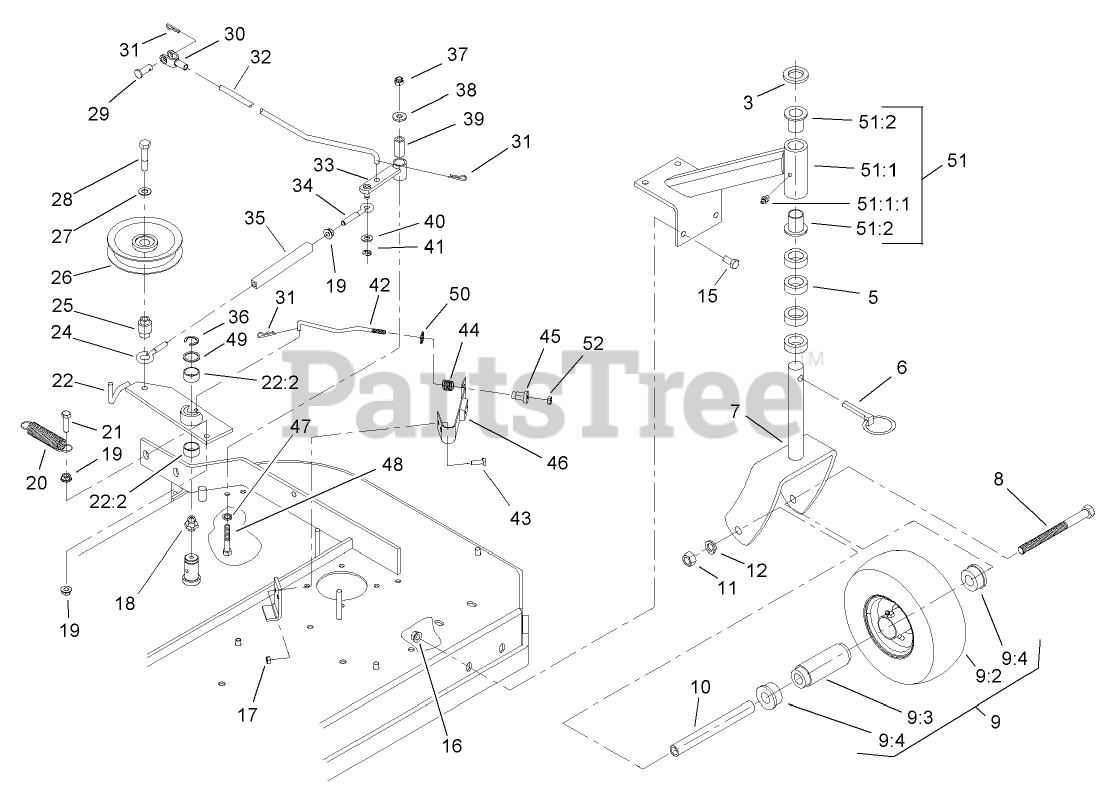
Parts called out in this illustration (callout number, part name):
3	WASHER-FLAT
5	SPACER-CASTER
7	FORK
8	SCREW-HH
9	WHEEL AND TIRE ASM
9:3	BEARING
9:4	BUSHING
10	SPACER
11	NUT-HH
12	WASHER-LOCK
15	SCREW-HH
16	NUT-HHF, WHIZ
17	NUT-LOCK, NI
18	FITTING-GREASE
19	NUT-HF
20	SPRING-EXTENSION
21	SCREW-HH
22	Idler Arm ASM
22:2	SLEEVE-BEARING
24	EYEBOLT-THREAD, LH
25	BUSHING-ENGAGEMENT
26	PULLEY-IDLER
27	WASHER-BELLEVILLE
28	SCREW-HH
29	PIN-CLEVIS
30	YOKE-ADJUSTABLE
31	PIN-COTTER
32	ARM-ASSIST, LINKAGE
33	ARM-ASSIST
34	EYEBOLT-THREAD, RH
35	BODY-TURNBUCKLE
36	RING-RETAINING, EXT
37	NUT-LOCK, NI
38	WASHER-FLAT
39	TUBE-PIVOT
40	WASHER-PLAIN
41	RING-RETAINING, EXT
42	ROD-BRAKE
43	SCREW-HH
44	SPRING-COMPRESSION
45	SPACER-FLANGED
46	PAD AND SPRING ASM
47	WASHER-SPRING
48	SCREW-HH
49	WASHER-SPINDLE
50	RING-PUSH ON
51	SUPPORT ASM
51:1	Support-Caster
51:1:1	FITTING-GREASE
51:2	BEARING-FLANGED
52	NUT-LOCK, NI
